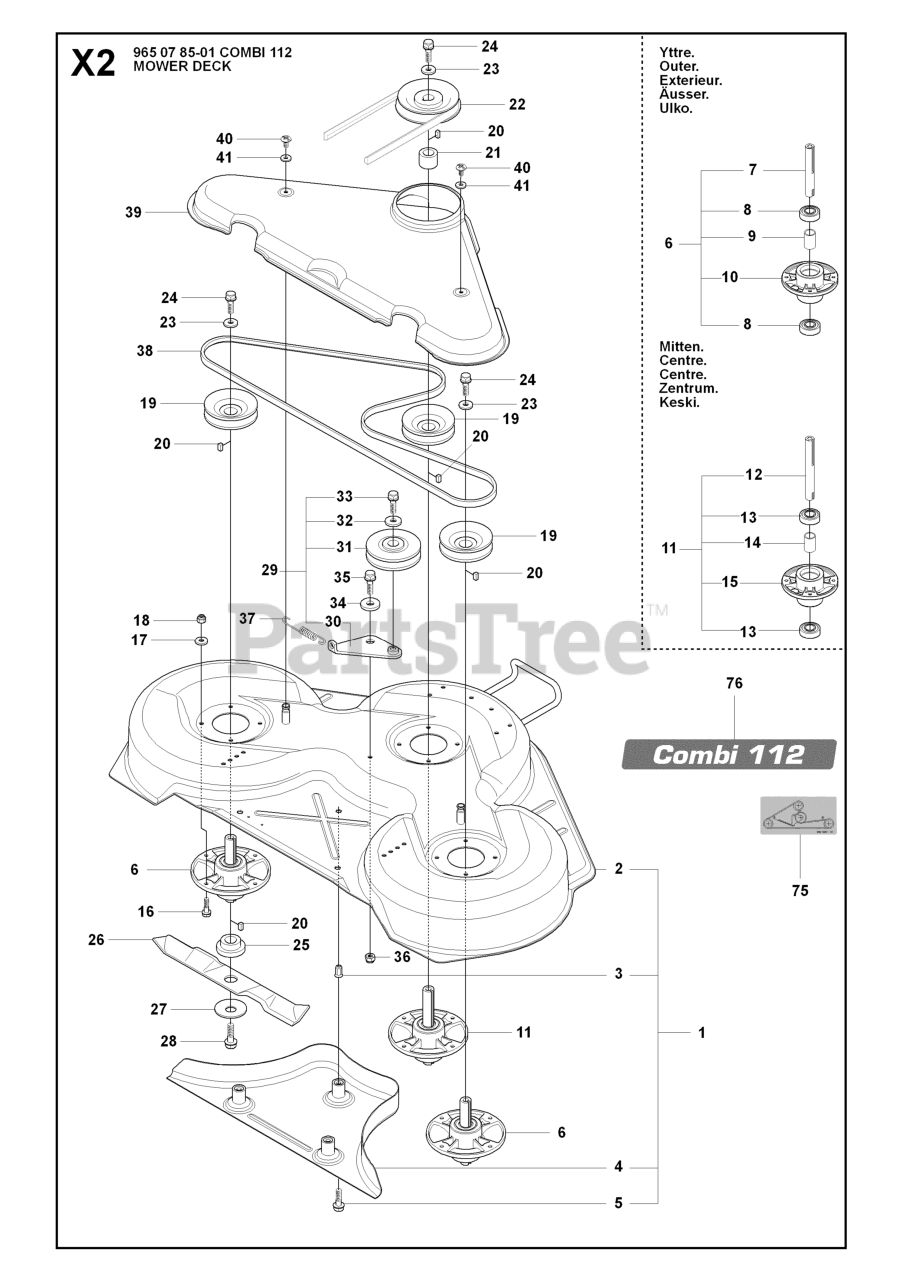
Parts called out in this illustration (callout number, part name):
1	CUTTING DECK C112 GREY RIDER
2	CUTTING DECK ASSY C112 GREY
6	RP SPINDLE ASSY
10	BEARING HOUSING
11	SPINDLE ASSY
15	BEARING HOUSING
17	WASHER BRB 8.4X17
18	LOCKNUT M8
27	WASHER
29	BELT TENSIONER ASSY
30	BELT TENSIONING ARM
34	WASHER
36	LOCKNUT M8
38	BELT
39	BELT COVER
